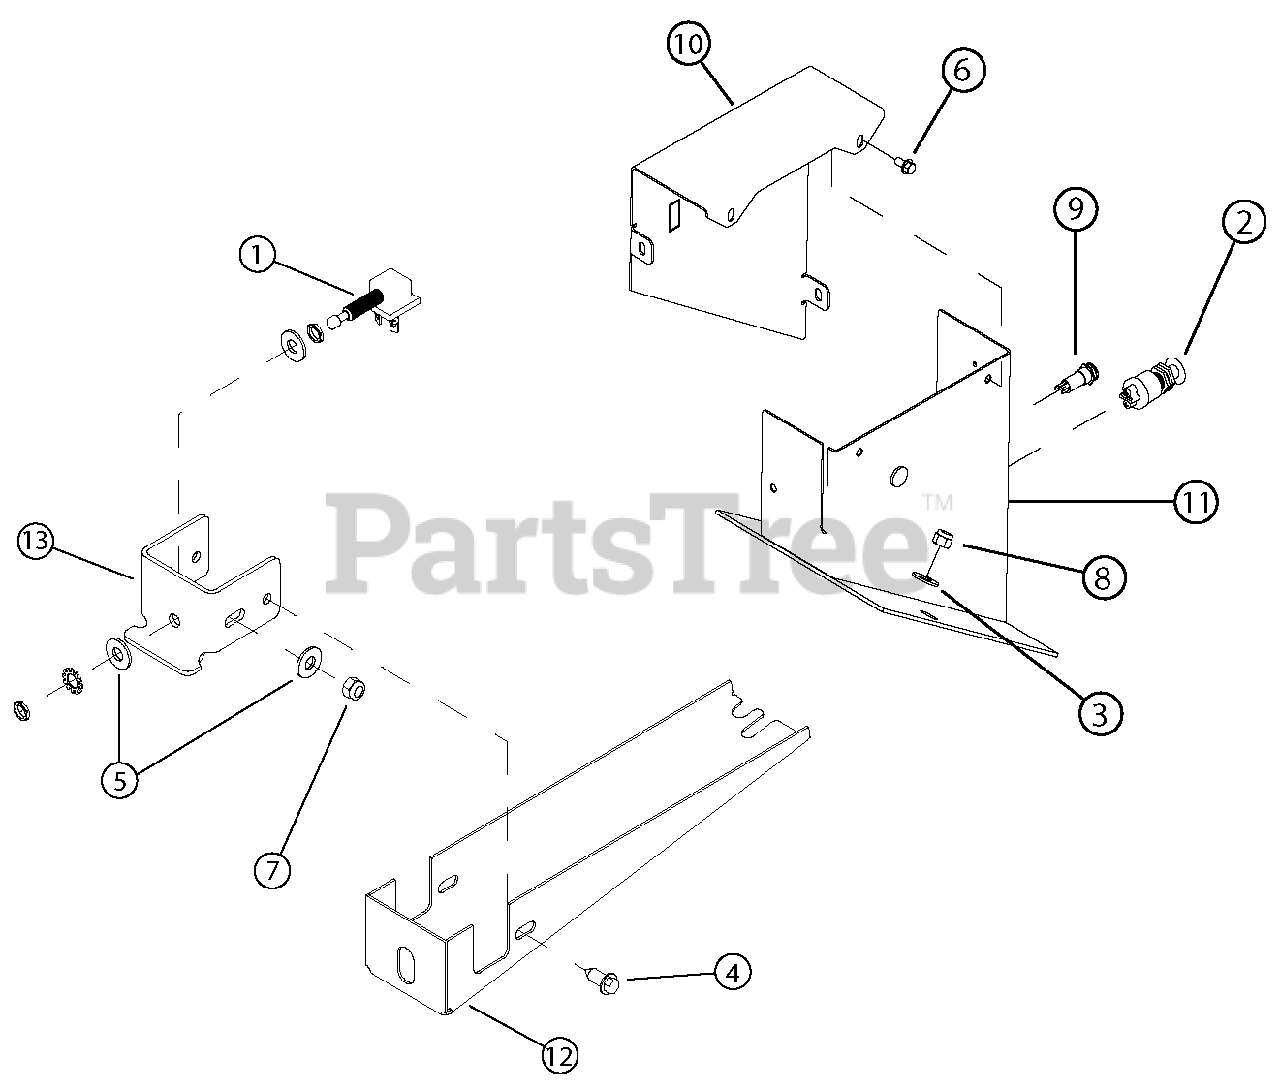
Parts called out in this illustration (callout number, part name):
1	SWITCH, N/C MOMENTATY PLUNGER
2	SWITCH, N/O MOMENTARY PUSHBUTTON
3	WASHER, 3/8 FLAT
4	SCREW, 11/32 X 7/8 HWH AB THREAD
5	WASHER, 5/16 FLAT
6	BOLT, SERR. FLANGE 1/4 X 1/2
7	NUT, 5/16 NYLOCK
8	NUT, 3/8 NYLOCK
9	LED, TRI-COLOR 12V 3-TERM BASE
10	PLATE, CONTROL BOX
11	WELDMENT, SWITCH MOUNT
12	SHIELD, KNEEBAR SWITCH
13	BRACKET, SWITCH
